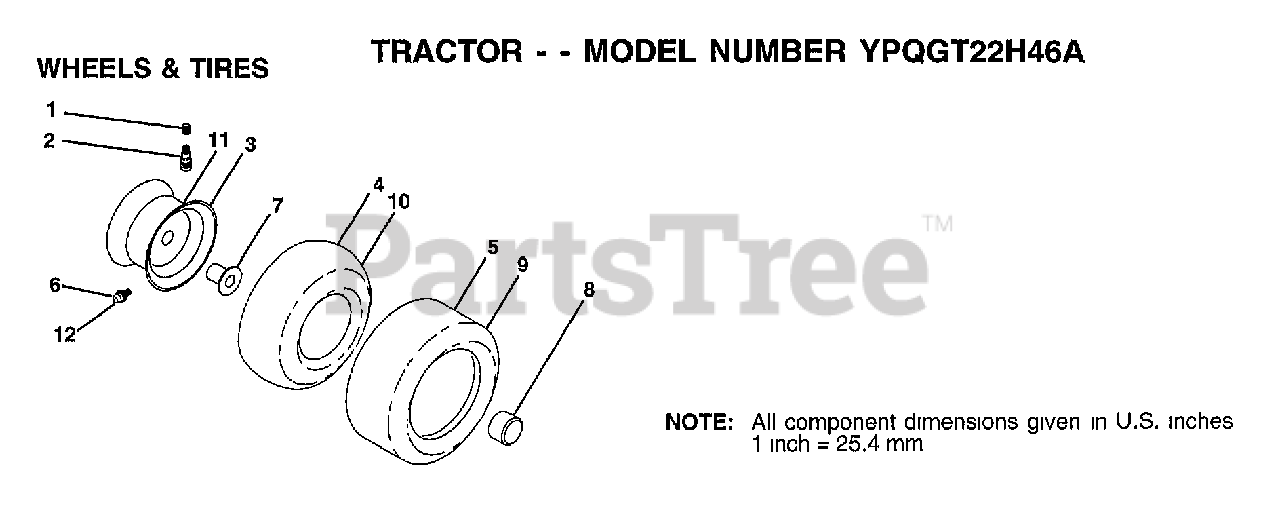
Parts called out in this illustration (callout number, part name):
1	VALVE CAP
2	VALVE STEM LT
3	"RIM ASM 8"" FRT"
4	TUBE.16X6.5/7.5-8
6	FITTING LT
7	"FLANGE, BEARING"
8	HUB CAP
10	TUBE.23X8/10-12
11	"RIM ASM 12"" REAR"
12	ZERK FITTING M
